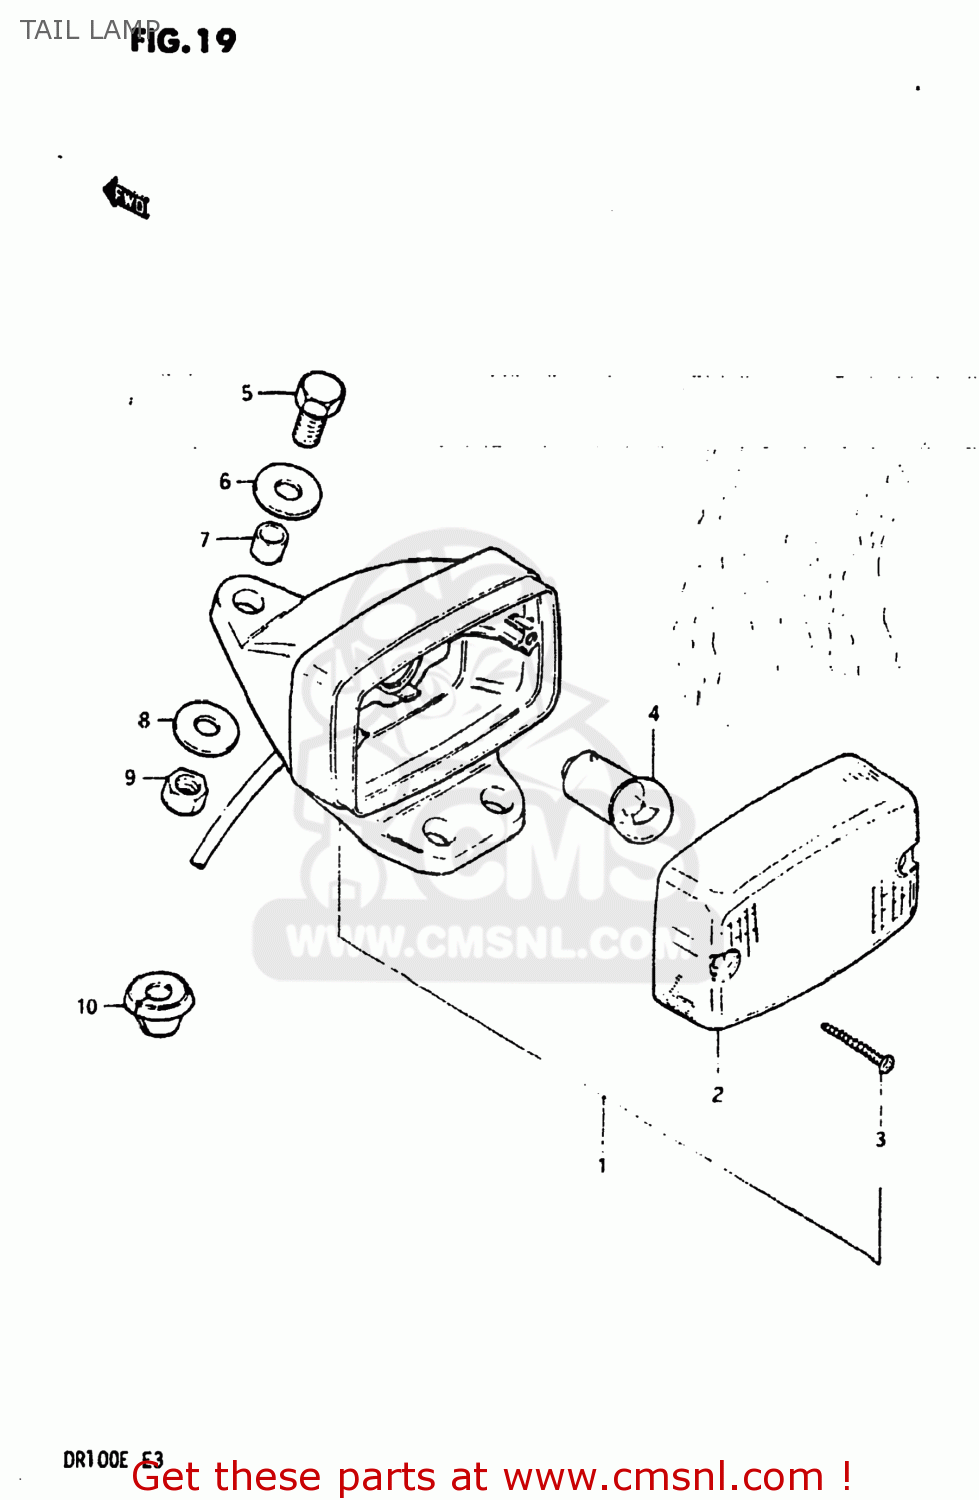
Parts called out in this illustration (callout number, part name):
1	LAMP ASSY,TAIL
2	LENS
3	SCREW
4	BULB(6V5W,TOKAI DENSO)
5	BOLT
6	WASHER
7	SPACER(6.1X9X7.5)
8	WASHER
9	NUT
10	GROMMET
